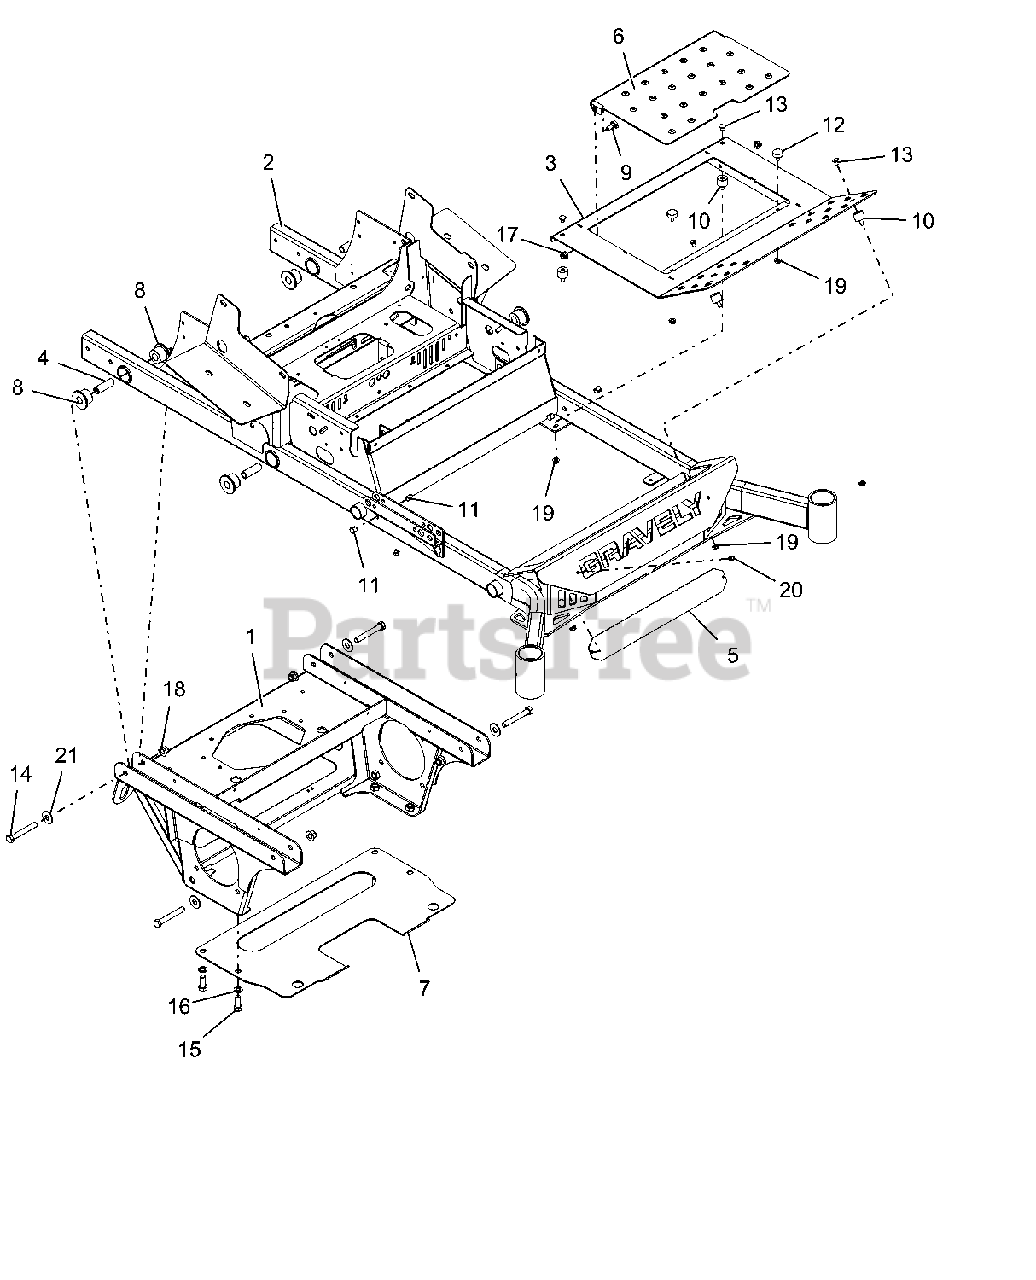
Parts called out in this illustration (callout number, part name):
1	WLDT, 200 PT AXLE/ENGINE FRAME
2	WLDMT, 52-66" PT400 MAIN FRAME-RED
3	FOOTPLATE WLDMT W/SAFETY DECAL
4	SPCR, .50 X .75 X 2.23 YZ
5	PLATE, BUMPER LOGO BACKING-BLACK
6	PANEL, INSPECTION
7	PLATE-TRANSMISSION SKID-RED
8	BSHG, FLANGE .750 X 1.510 X 1.130 X 2.000
9	BLT, SHLDR EP .38-16X.30 HEX YZ
10	BUMPER, STUD MOUNTED W/FEMALE INSERT
11	PLUG, HOLE .500
12	BUMPER, RUBBER
13	BLT-RDHDSQNK .31-18X.50 G5 YWZC
14	BLT-HEX .50-13X3.50 GR5 YWZC
15	BLT-HEX .50-13X1.25 GR5 YWZC
16	WSHR-LK .50X.125 REG YWZC
17	NUT-LK-NYL-FLG .38-16 YWZC
18	NUT-LK-NYL-FLG .50-13 YWZC
19	@NUT-SPNLK-FLG .312-18 YWZC
20	SCR-TAP .25-20X.50 HWH TR YWZ
21	WSHR-FL-STL.563X1.38X.109YWZC
